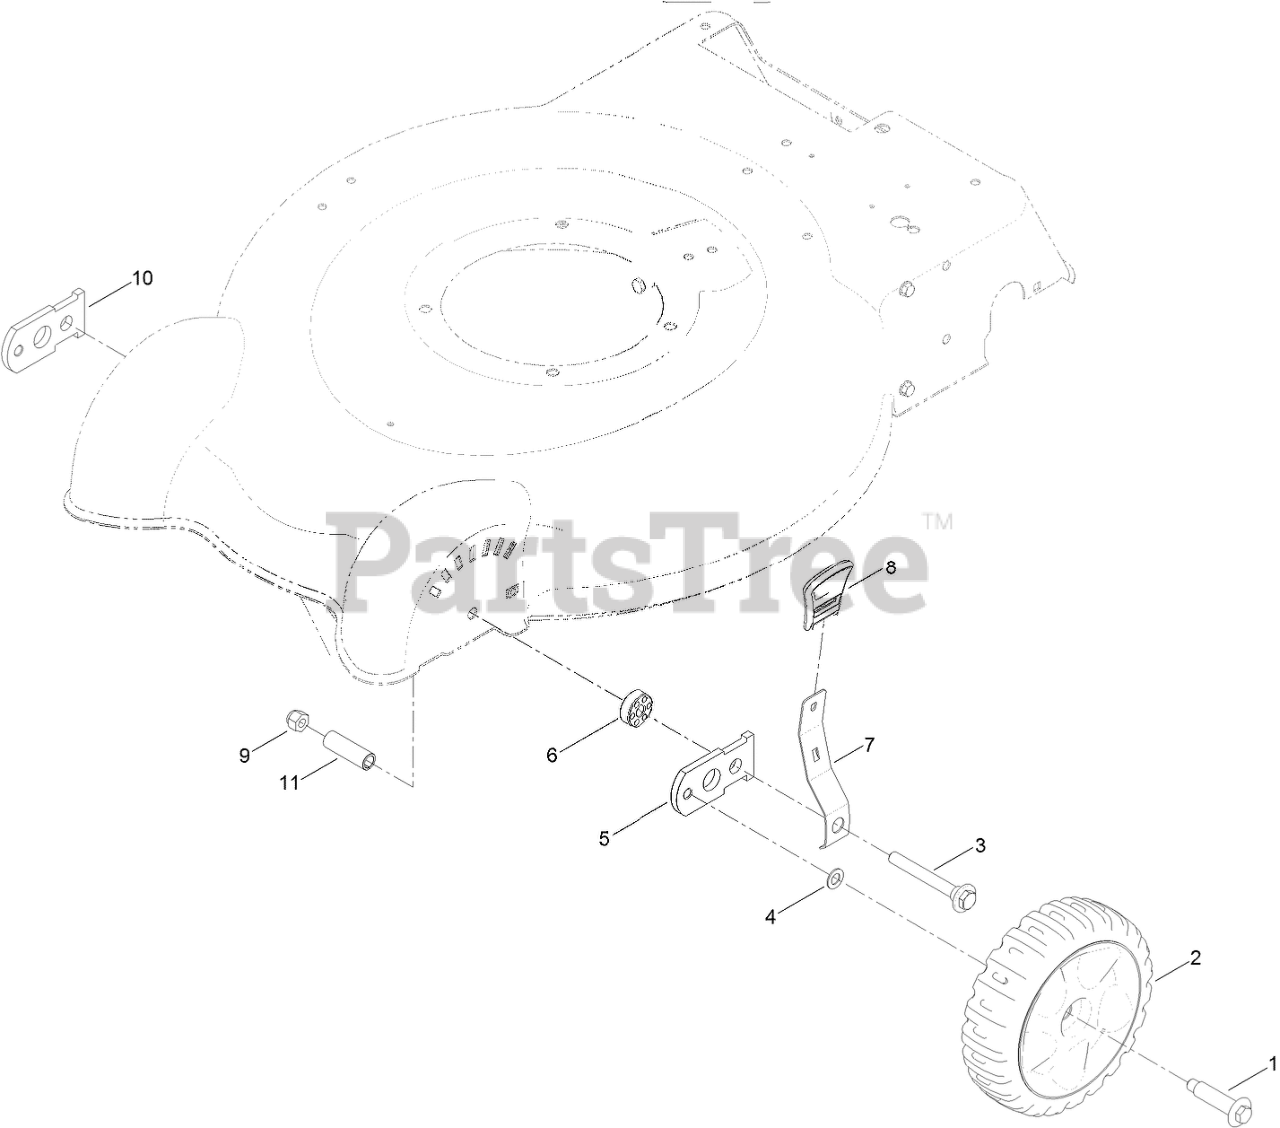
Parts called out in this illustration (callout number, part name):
1	BOLT-SHOULDER
2	7 INCH WHEEL AND TIRE ASM
3	BOLT-SHOULDER
4	WASHER
5	ARM-PIVOT, RH
6	SPACER-ARM, PIVOT
7	ARM-SPRING, FRONT
8	KNOB-HOC
9	NUT-LOCK, NI
10	ARM-PIVOT, LH
11	SPACER-BAFFLE, FRONT
